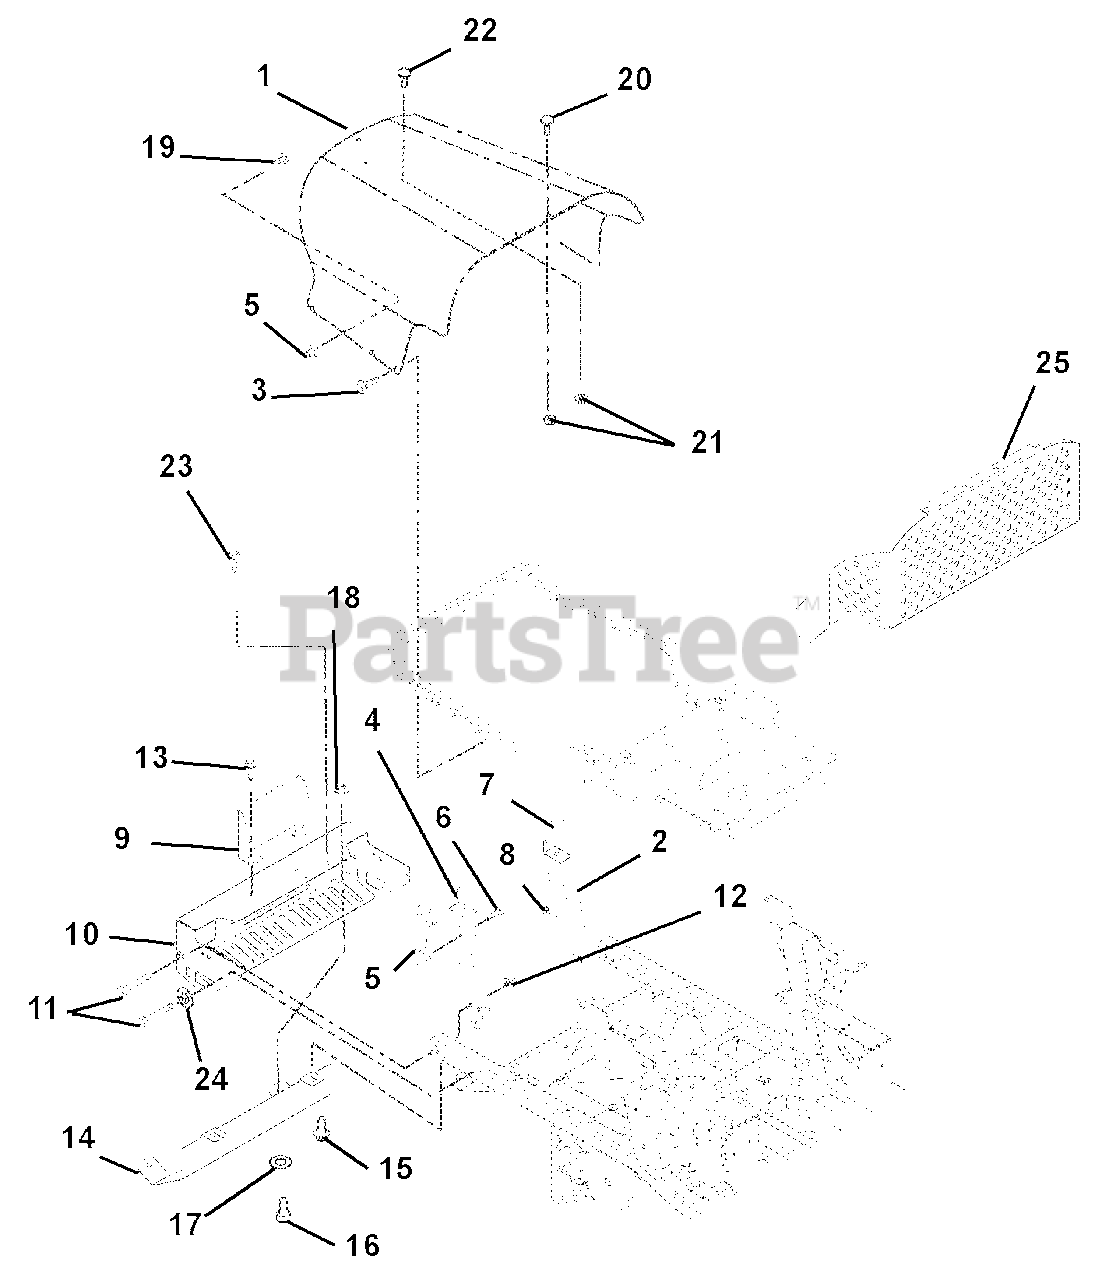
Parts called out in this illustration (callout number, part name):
2	Weldment, Hood Support, Left Hand
3	Screw, Tapping .38-16 x .75 Hex Washer Head
4	Weldment, Hood Support Right Hand
5	Latch, Rubber
6	Screw, Machine 10-24 x .50 Hex Washer Head
7	Button Bumper
8	Nut, Spin Lock Flange .312-18
9	Guard, Muffler
10	Bumper, Rear
11	Bolt, Hex .38-16 x 2.75 Grade 5
12	Nut, Locking Top Flange .38-16
13	Screw, Tapping .38-16 x .75 Hex Washer Head
14	Heat Shield
15	Screw, Tapping .38-16 x .50 Hex Washer Head Thread Rolling YWZ
16	Bolt, Hex .38-16 x .75 Grade 5
17	Washer, Flat Steel .438 x1.00 x .083 YWZ
18	Nut, Locking Top Flange .38-16
19	Screw, Machine 10-24 x 1.50 Hex Washer Head
20	Bolt, Round Head Square Neck .25-20 x .50 Grade 5
21	Nut, Locking Top Flange .25-20
22	Bolt, Round Head Square Neck .25-20 x .75 Grade 5
23	Screw, Tapping .25-20 x .50 Hex Washer Head Thread
24	Washer, Flat Steel .406 x .812 x .065
25	Plenum, Hood
